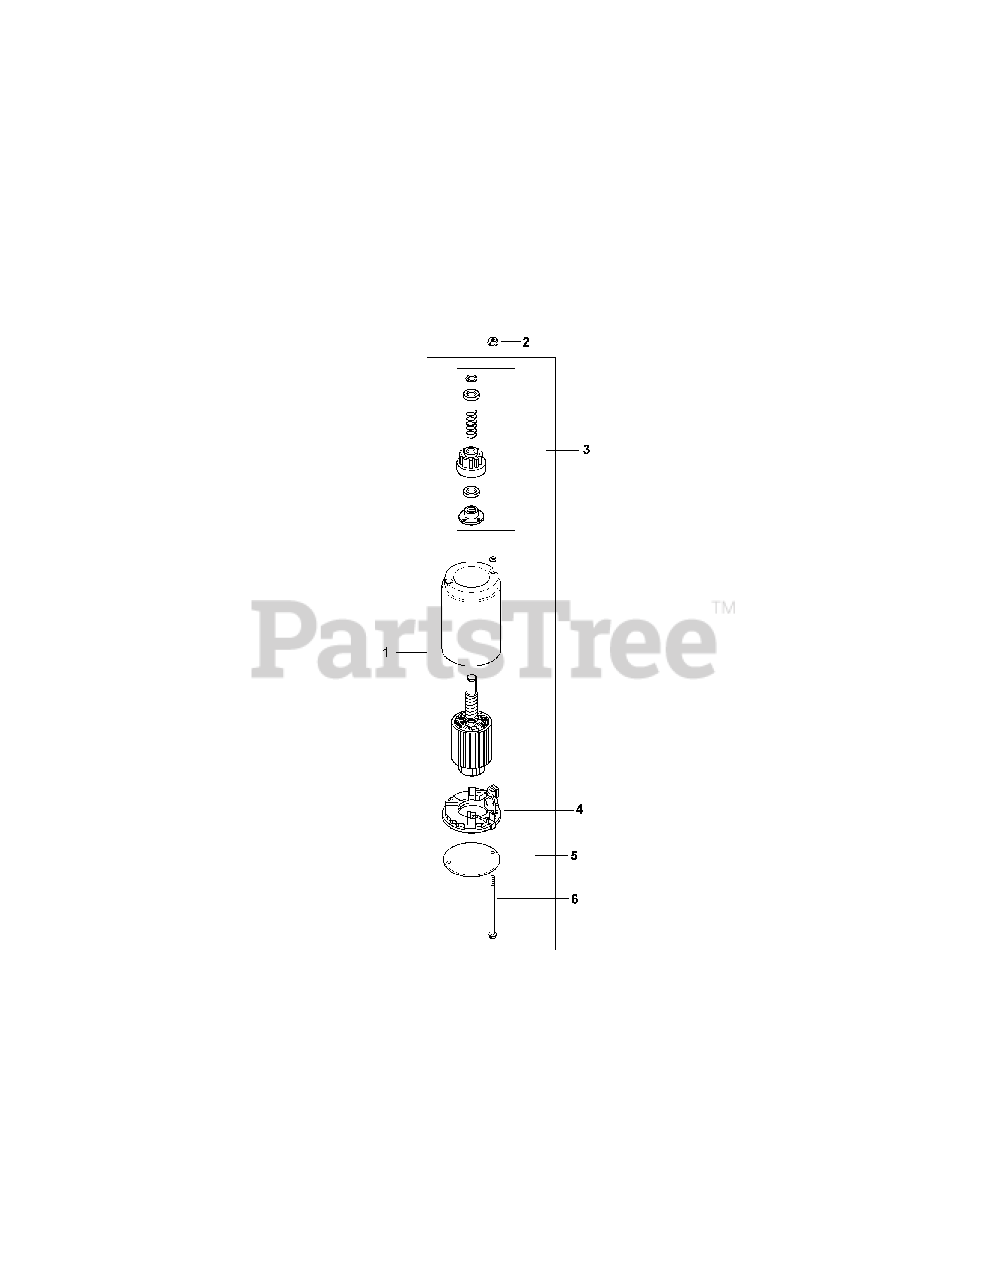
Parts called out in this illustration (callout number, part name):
1	Starter Assembly (Inc. 3-6)
2	Free Spinning Flg. Nut, #10-24
3	Drive Kit (J.E.)
5	Drive End Cap (J.E.)
